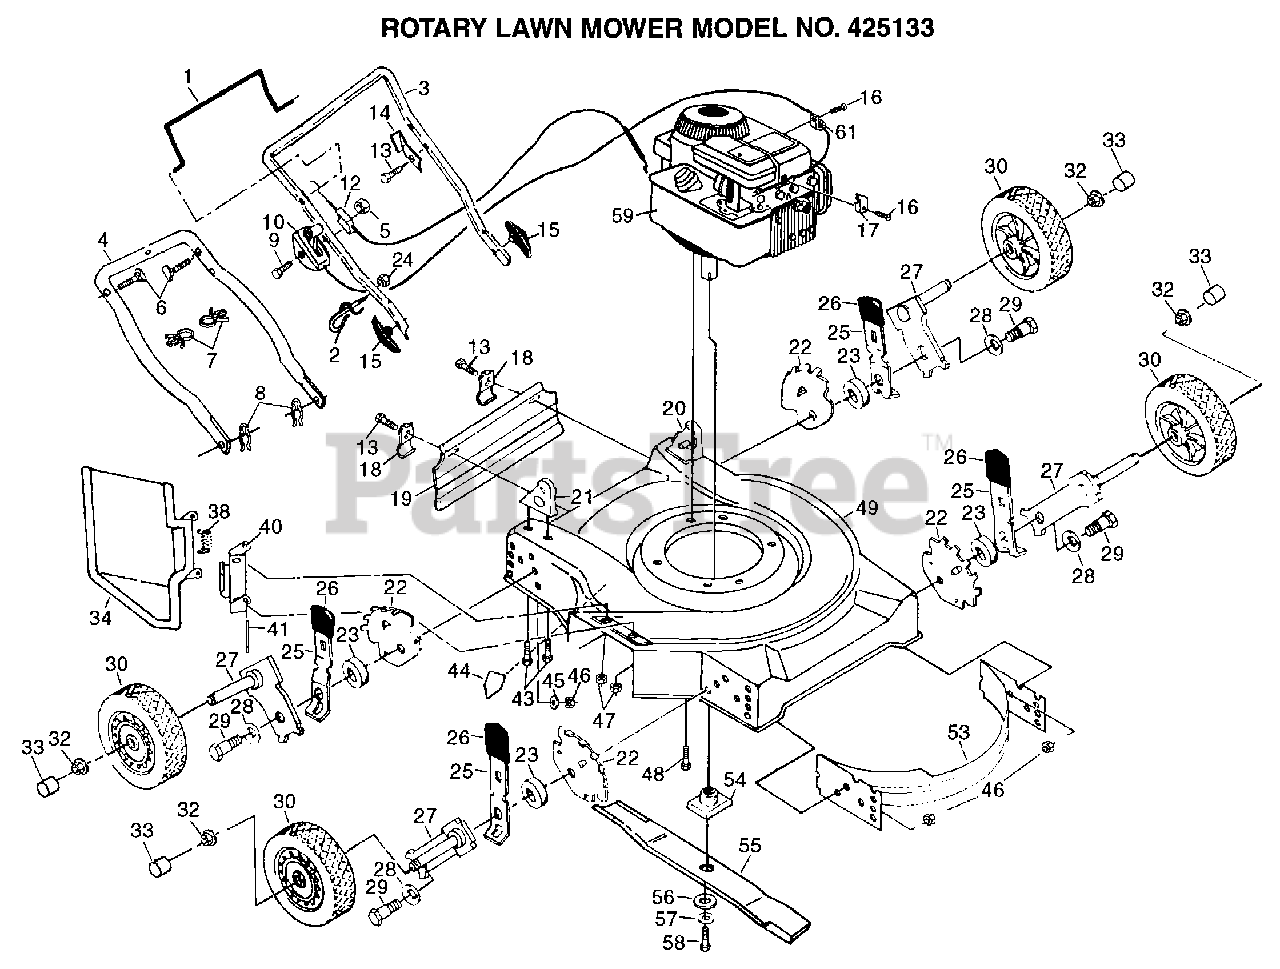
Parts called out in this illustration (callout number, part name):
1	CONTROL BAR PM
2	ROPE GUIDE
6	BOLT.HANDLE.LM
8	HAIRPIN COTTER
9	SCREW.HXHD.WASH.
10	CONTROL THROTTLE
12	"CABLE,ENG ZONE CO"
13	TAPPING SCREW
14	"BRKT,UPSTOP"
15	KNOB HANDLE
16	SCREW PM
17	CABLE CLAMP
18	"BRKT,DEFL PM"
19	SKIRT.REAR.FGD.22
20	HDLE BRKT ASSY LH
21	HDLE BRKT ASSY.RH
22	BRACKET.ADJ.9POS.
23	SPACER.HEIGHT.ADJ
24	NUT
25	SPRING SELECTOR
26	KNOB PM
27	ARM.AXLE.ASM.BZP.
28	"WASHER, BELLEVIL."
29	BOLT.SHLD.W/PATCH
30	WHEEL.ASM
32	HEX FLANGE LOCKNT
33	HUB CAP-PLASTIC
34	GUARD.DISCH.22SD.
40	BRACKET.HINGE.W/F
41	ROD.HINGE.COMBI-C
43	SCREW 5/16-18X3/4
44	DECAL-DANGER PM
48	BOLT.ENG.3/8-16
49	MOWER HSG KIT
53	BAFFLE.FRT/REAR
54	BLADE ADAPTOR
55	"BLADE.MULCH.22"""
56	"WASHER,HARDEN"
57	LOCKWASHER
58	SCREW
61	GUIDE CLIP PM
